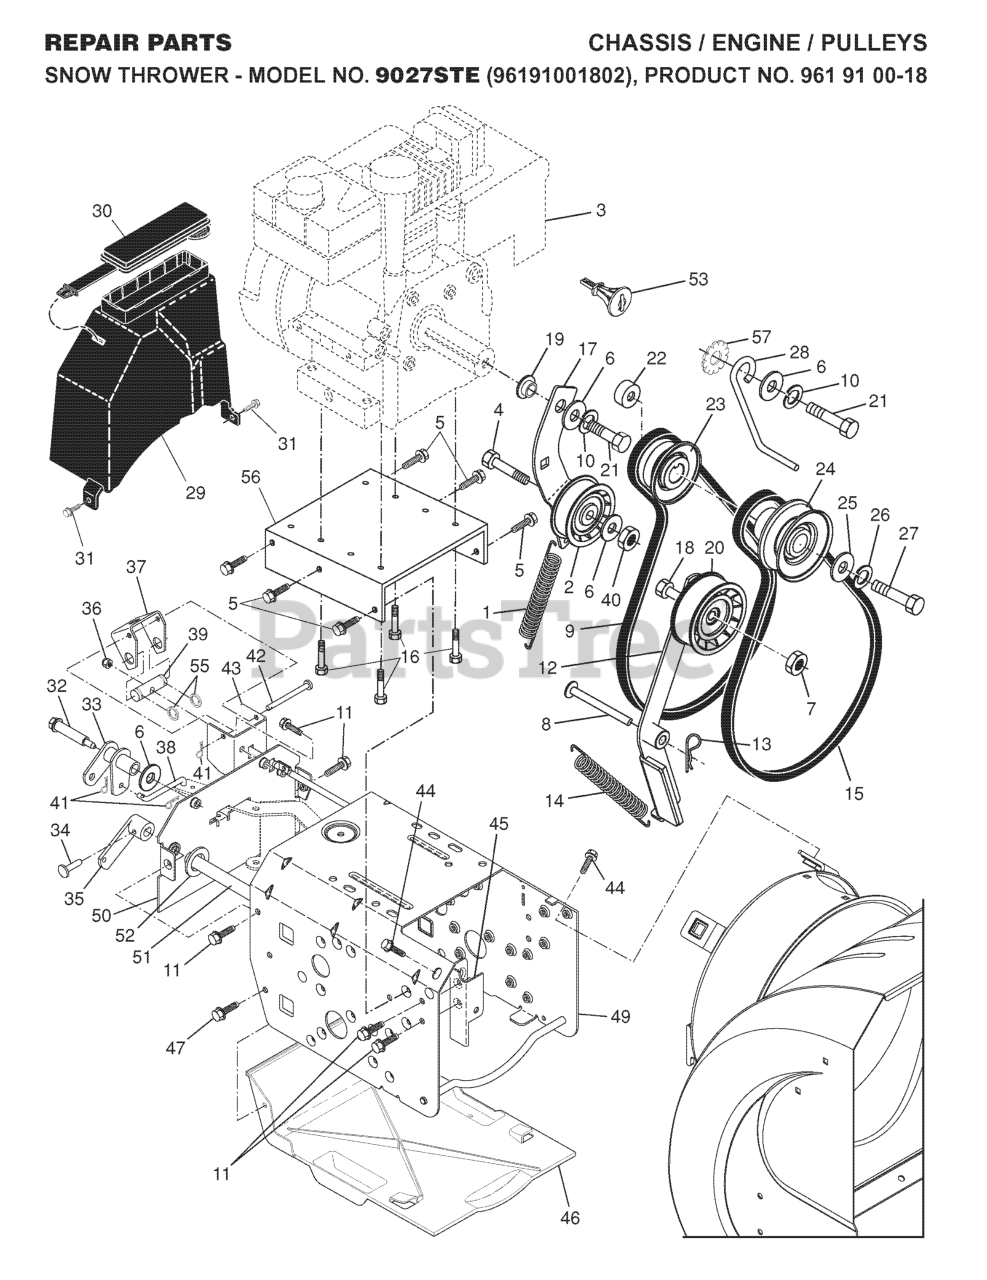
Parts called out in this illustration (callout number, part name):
1	RP SPRING, TRACTION IDLER
2	PULLEY.W/SPACER.2.25
4	BOLT.5/16-18X1-1/4 FULL.THREAD
5	SELF-TAPPING SCREW 5/16-18X3/4
6	STEEL WASHER
7	LOCKNUT 5/16-18
8	PIN, IDLER PIVOT
10	WASHER.LOCK.HVY.HLCL.SPR.5/16
11	Screw 5/16-18 x 1/2 Hex, Self Tapping 5/16-18 x 1/2
12	ARM PAD ASSY
13	RETAINER CLIP PM
14	SPRING, BRAKE
15	BELT.V.IMPELLER
16	BOLT 3/8-16X1-1/8
17	IDLER ARM
18	HEX BOLT
19	RP BUSHING, IDLER PIVOT
20	PULLEY.W/SPACER.2.75
22	SPACER.ENGINE.PULLEY
23	PULLEY,ENGINE TRACTION DRIVE
24	PULLEY, ENGINE IMPELLER DRIVE
25	WASHER, FLAT 3/8
26	LOCKWASHER
27	SCREW, HEX HD 3/8-24 X 1-3/8
28	BELT.GUIDE.RH
29	COVER.ASM.BELT/STORAGE
30	COVER.STORAGE.SNOW
31	SCREW
32	BOLT, SHOULDER 5/16-18
33	BELLCRANK SHIFTER
34	CLEVIS PIN
35	ARM, AUGER CONTROL
36	NUT.71038.31-18.HEX.NYLOCK
37	BRACKET, PIVOT
38	LINK, SPEED CONTROL
39	TRUNNION, TRACTION
41	RETAINER CLIP
42	PIN, PIVOT BRACKET
44	SCREW 3/8-16X1
45	BRACKET, IDLER PIVOT
46	PAN.BOTTOM.PLASTIC
47	SCREW, HEX HEAD, TAPPING
48	NUT.CENTERLOCK.5/16-
49	FRAME.WELD.PNT.003BGP
50	PLATE, FRAME END
51	SHAFT, AUGER CONTROL
52	THRUST WASHER
53	KEY.PUSH/PULL.B&S.283707
55	RETAINING RING LT
56	PLATE.ENGINE.MOUNT.PNT
57	WASHER EXT TOOTH LOCK 5/16
